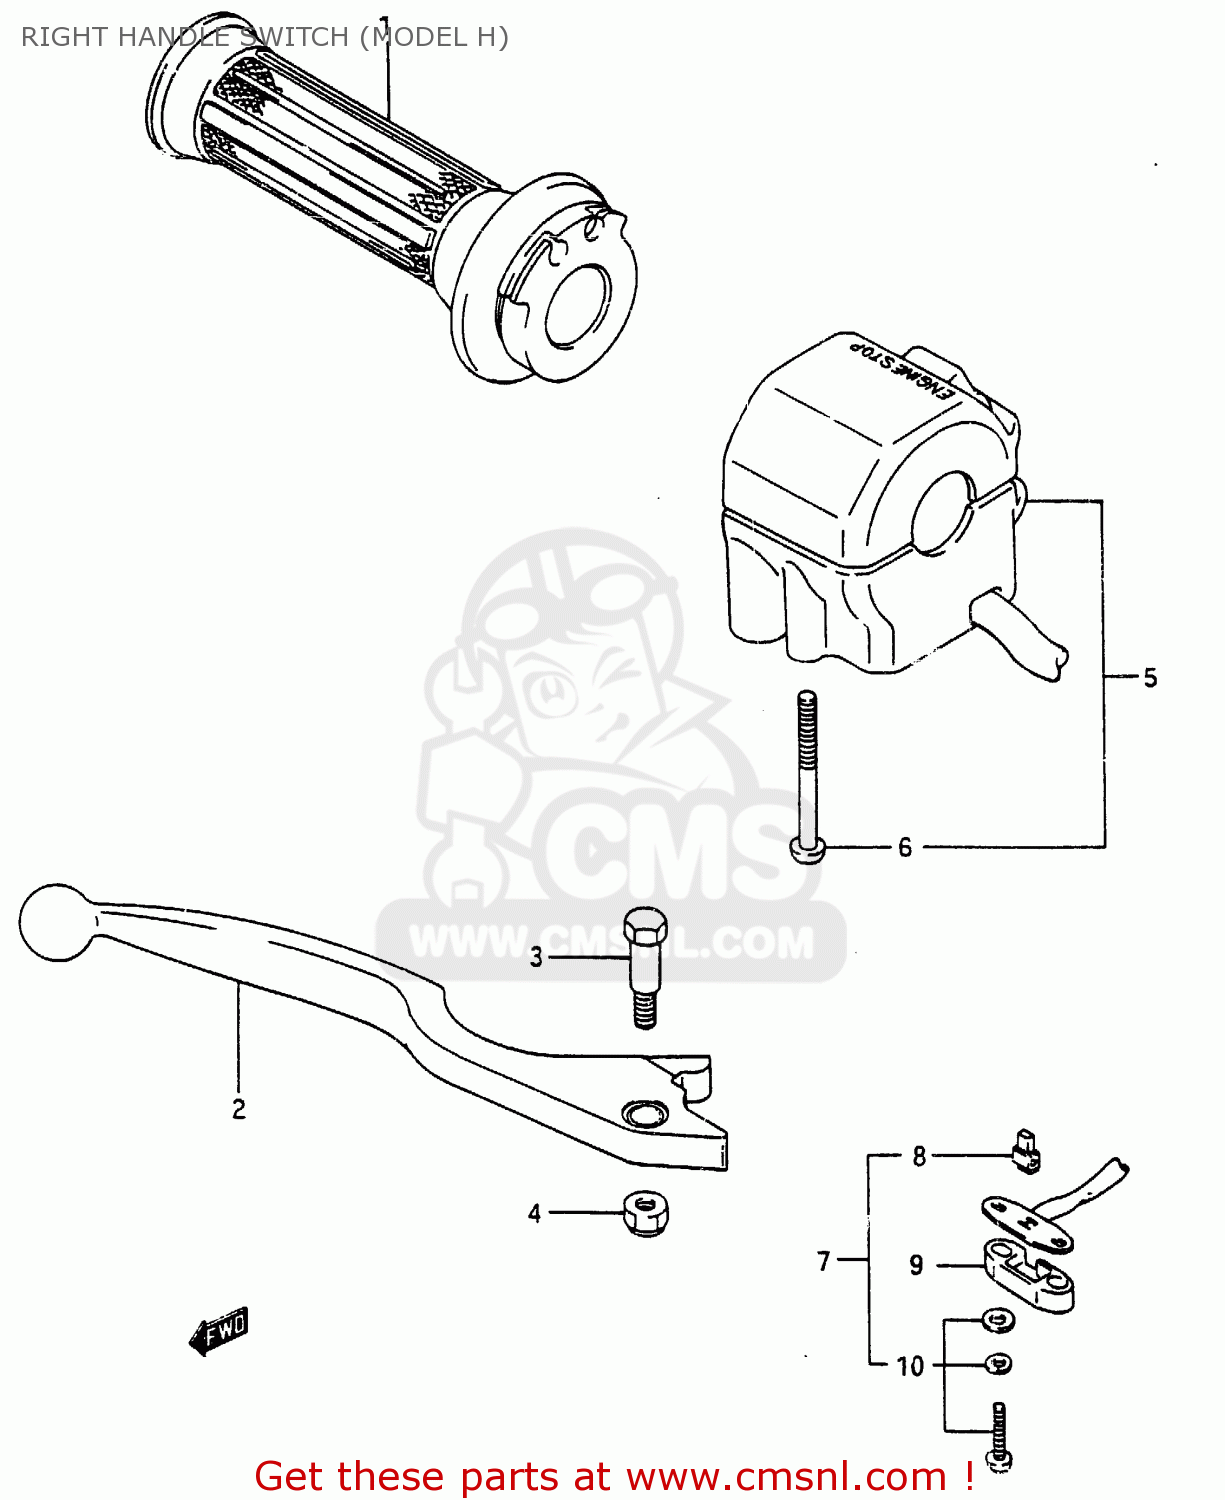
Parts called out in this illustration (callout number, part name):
1	GRIP,THROTTLE
2	LEVER,BRAKE
3	BOLT,LEVER PIVOT
4	NUT
5	SWITCH ASSY, HANDLE RH
6	SCREW, 5X45
7	SWITCH ASSEMBLY
8	CONTACT,SWITCH
9	COVER,FR BK TERMINAL BASE
10	SCREW
